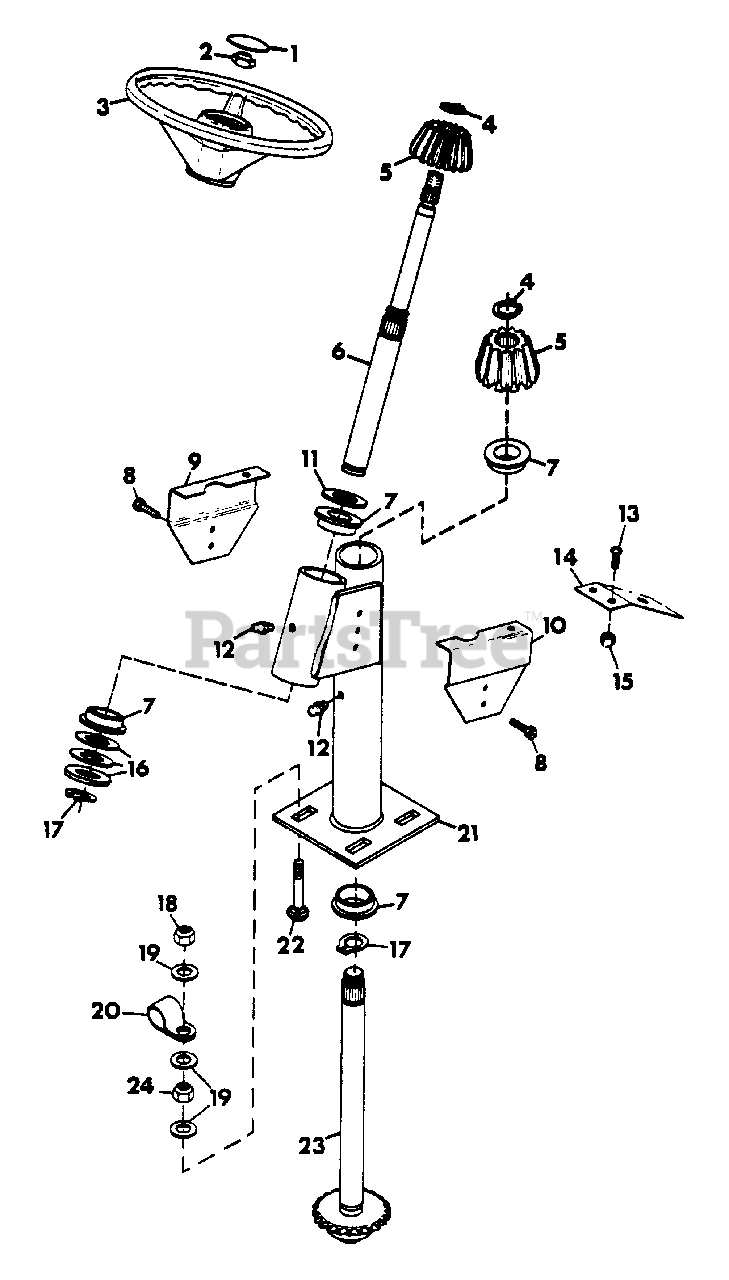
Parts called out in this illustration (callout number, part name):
1	CAP, STEERING WHEEL
2	NUT, JAM 5/8-11
3	WHEEL, STEERING
4	RING, RETAINING
5	PINION, BEVEL
6	SHAFT, STEERING WHEEL
7	BEARING, FLANGED
8	SCREW, TAPPING 10-24X.50
9	GUARD, STEERING R.H.
10	GUARD, STEERING L.H.
11	BEARING, THRUST RACE .030
12	FITTING, LUBE 1/4-28
13	SCREW, MACHINE 1/4-20X.625
14	BRACKET, IGNITION
15	NUT, LOCK 1/4-20
16	RACE, BEARING THRUST
17	RING, RETAINING
18	NUT, LOCK 3/8-16
19	WASHER, FLAT .406X.812X.065
20	CLAMP, NYLON
21	TUBE, STEERING
22	BOLT, 3/8-16X1.50 RD HD SQ NK
23	WELDMENT, STEERING SHAFT
24	NUT, HEX 3/8-16
